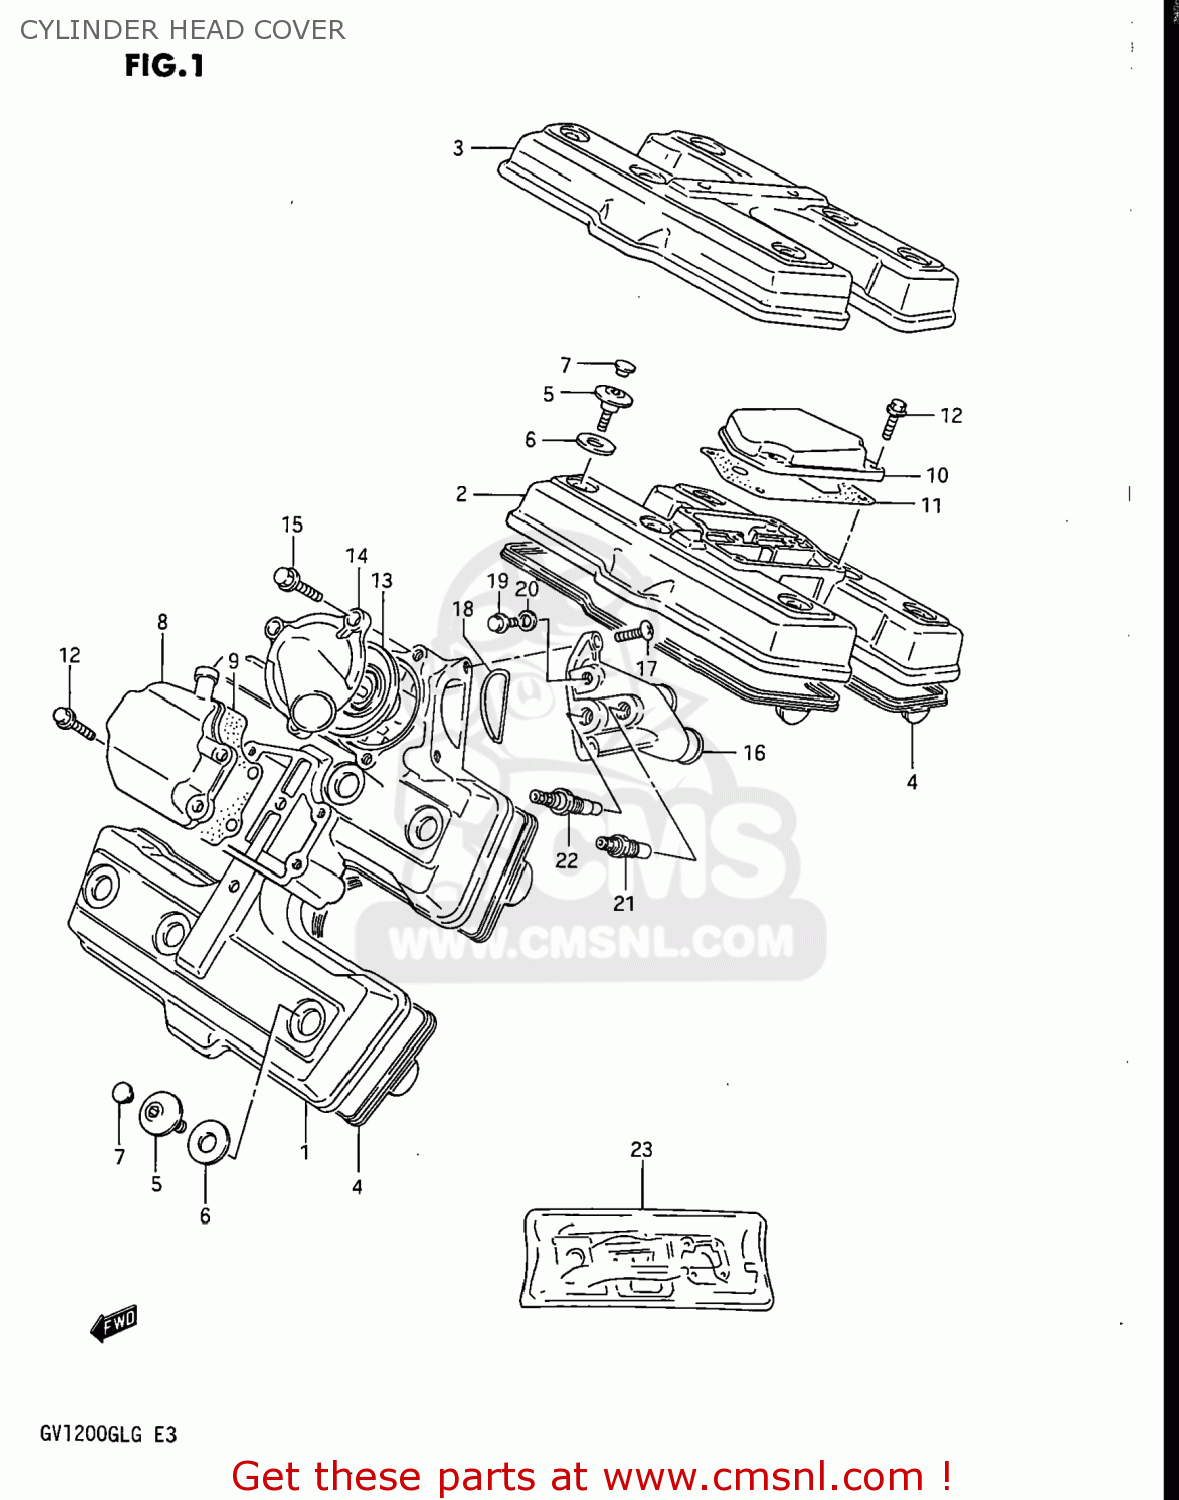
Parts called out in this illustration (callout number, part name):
1	COVER,CYLINDER HEAD
2	COVER,CYLINDER HEAD
3	COVER,CYLINDER HEAD
4	GASKET,CYLINDER HEAD COVER (NAS)
5	BOLT(7X5.5)
6	WASHER
7	CAP(OD:10)
8	GASKET
9	GASKET,BREATHER COVER (NAS)
10	COVER,BREATHER
11	GASKET (NAS)
12	BOLT,REAR
13	THERMOSTAT,WATER
14	COVER,THERMOSTAT
15	BOLT
16	CONNECTOR,THERMOSTAT,INLET
17	SCREW
18	O-RING,THERMO CONNECTOR
19	UNION
20	GASKET(6.2X11X1).2 (NAS)
21	SWITCH,RADIATOR FAN
22	GAUGE ASSY,WATER TEMP
23	GASKET SET
